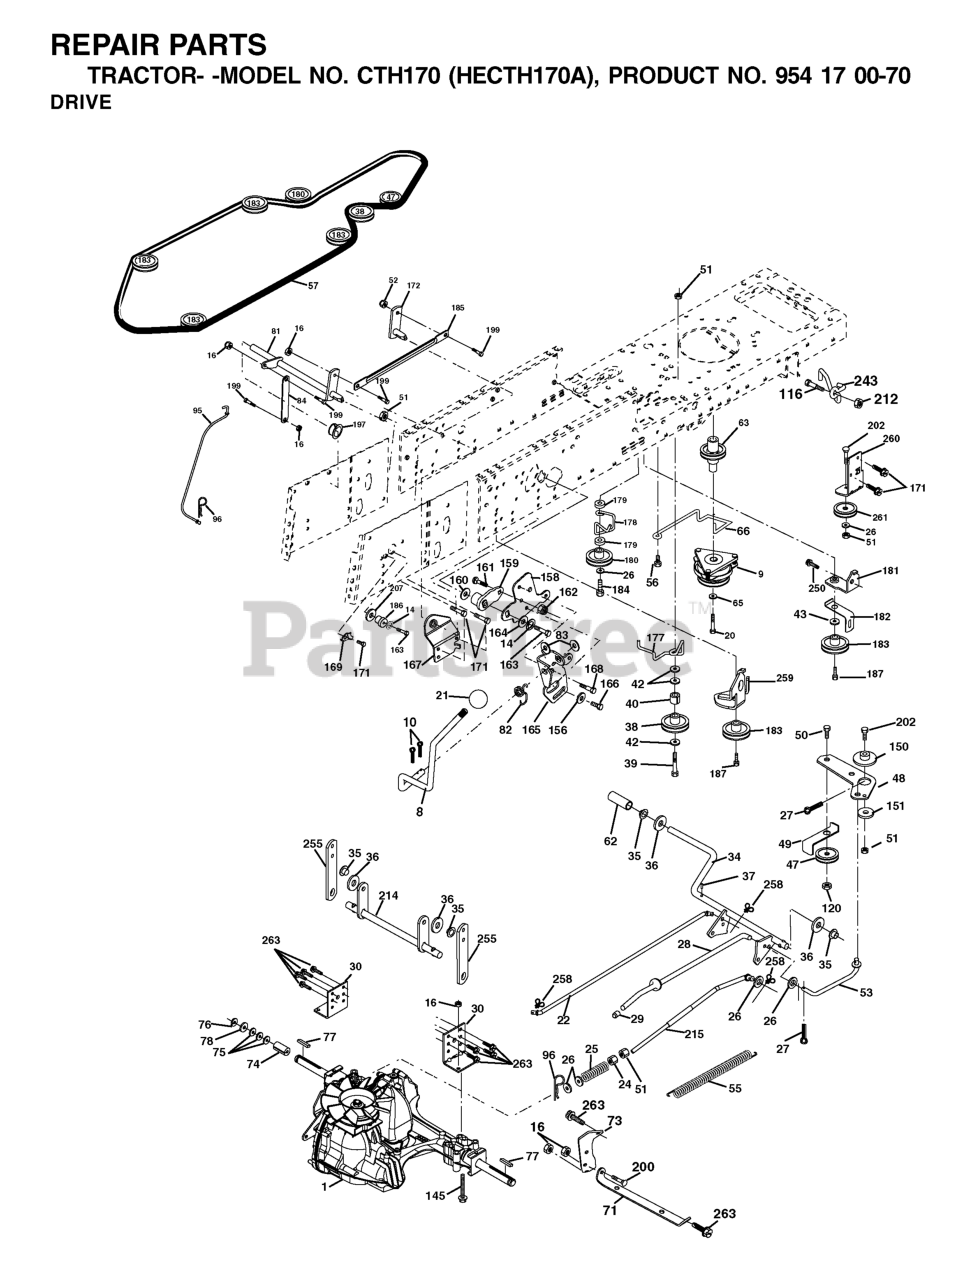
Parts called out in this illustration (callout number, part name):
8	ROD.SHIFT.FENDER.ADJ.LT.CRD
10	PIN COTTER
14	LOCKWASHER
16	NUT.71038.31-18.HEX.NYLOCK
20	BOLT
21	KNOB.DUCKHEAD.1/2
22	ROD
24	NUT
25	SPRING ROD LT
26	WASHER
27	COTTER PIN
28	ROD, PARKING BRAKE
29	PLUNGER CAP
30	BRKT, TRNSXLE MNT 20"
34	SHAFT, FOOT PEDAL
35	BEARING.NYLON
37	DRIVE PIN
38	PULLEY.FLAT
42	WASHER
47	IDLER PULLEY
48	BELLCRANK, CLUTCH
49	RETAIN BELT
50	BOLT
52	LOCKNUT
53	LINK, CLUTCH LT
55	SPRING, RETURN LT
56	SCREW.3/8-16
57	V-BELT 113"
62	COVER, PEDAL (1 2)
63	PULLEY.ENGINE.CVX.LT
65	LOCKWASHER
66	KEEPER BELT ENGINE
71	STRAP TORQUE LH HYDRO
73	STRAP TORQUE RH HYDRO
74	SPACER AXLE
77	SQUARE KEY
81	ASM.CROSS.SHAFT.REAR.CRD.0510
82	SHIFT SPRING
83	WASHER
84	LINK.PNT.TRANSAXLE.0510.CRD
95	LINK
96	RETAINER M
116	BOLT D
120	NUT LOCK FLG 3/8-16 UNC
145	BOLT HEX 5/16-18 GR 5
150	BUSHING.BELLCRANK.GRD.DR
151	WASHER 12/32X2X10GA
156	WASHER.SRRTD.5/16
158	BRACKET
159	HUB
160	Washer 29/32 x 1 - 1/4 x 16 Ga.
161	BOLT
162	NUT.CROWNLOCK.1/4
164	Washer 5/8 x .281 x 10 Ga.
165	RP BRACKET
167	BRACKET.SUPT.SHIFT.CRD
168	BOLT.SHOULDER.5/16-18X
169	PLATE.FASTENING.CROSS.SHAFT
172	LINK
180	PULLEY.FLAT.IDLER
181	BRACKET
182	KEEPER BELT
184	SCREW.HXWSH.3/8
185	LINK
186	HUB.TAPERED.ROUND.CRD
187	BOLT.5/16-18X1.25
197	NYLINER SNAP 5/8" ID
199	BOLT SHOULDER 5/16-18 UNC
206	WASHER
207	WASHER NYL
212	NUT
214	LEVER
215	ROD
243	BRKT ASM MTNG
250	SCREW 3/8-16X3/4
255	SHAFT
258	CLIP RETAINER
259	BRACKET
261	PULLEY.IDLER.FLAT
263	SCREW, 3/8-16X3/4
